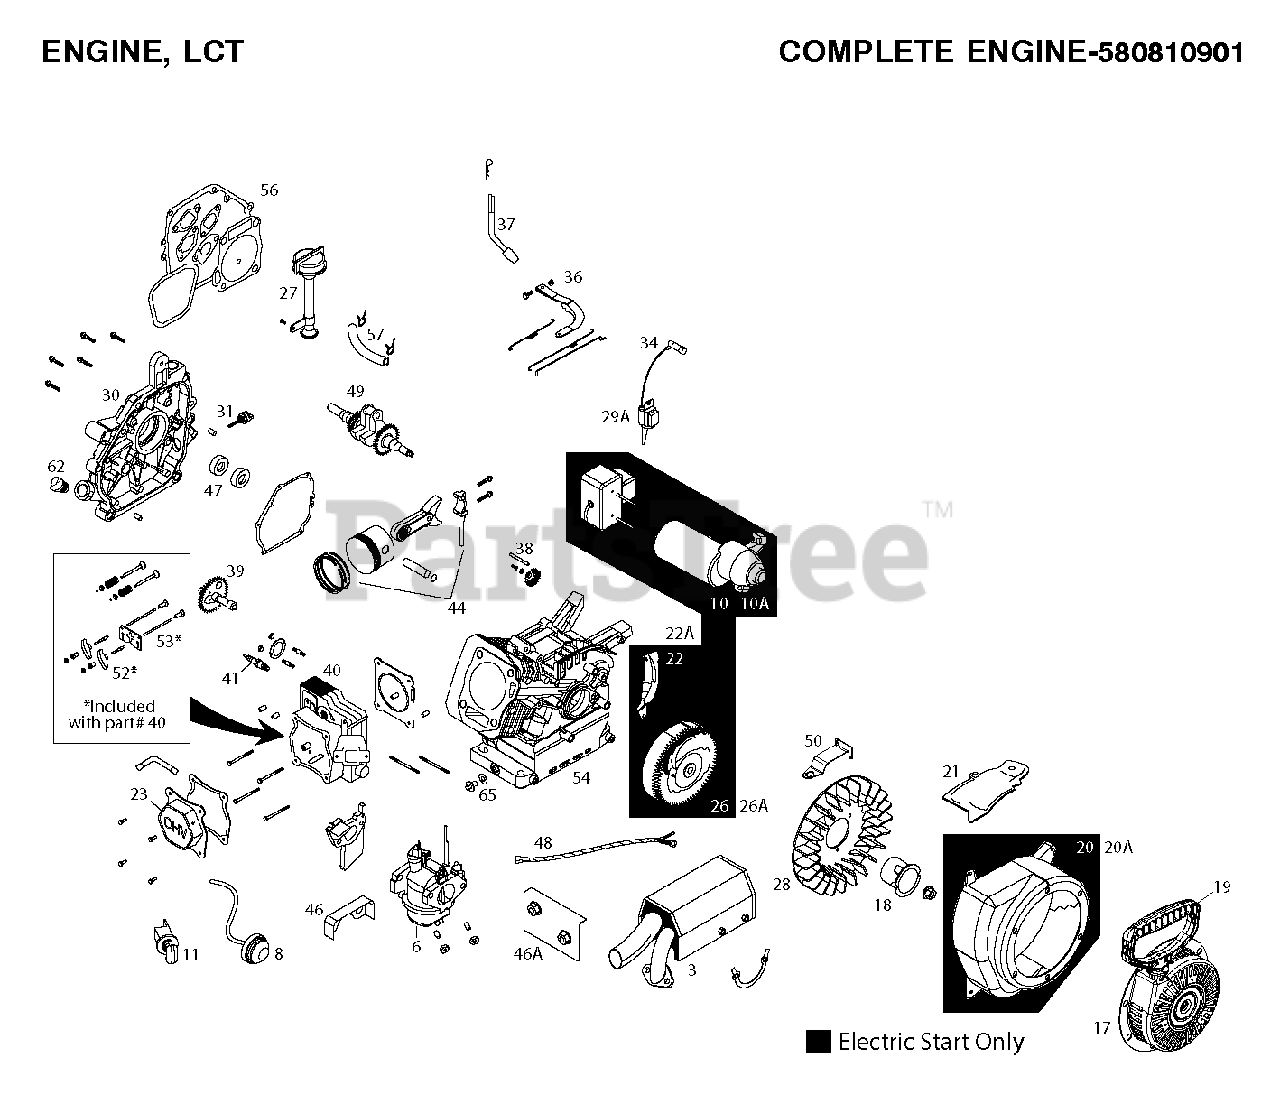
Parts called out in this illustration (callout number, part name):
3	MUFFLER.ASM.LCT.208CC.SNGL.STG
6	CARB.ASM.SS/SNO.LCT(SKSNO313)
8	BULB.FUEL.PRMR.W/HOSE(SKSNO306
10	STARTER.ASM.ELEC.(SKSNO411)
10A	STARTER STARTER.EURO
11	SWITH.KEY.ASSEM.SNOW.SINGLE.ST
17	RECOIL.STRT.ROUND(BLK) SNOW
18	STRTER.CUP(NON-SLOT)SKSN0601.2
19	STARTER.GRIP.SNOW.LCT.SKSN0603
20	BLOW.HSG.ASSY.ELECSKS
20A	BLOW.HSG.ASSY.ELEC(SKSN-0612)
21	SHILED.FLYWEEL.SYS(SKSN-0604)
22	SHLD.ELEC.START.FLY(SKSN-0605)
22A	SHIELD.FLYWEEL.MAN(SKSN-0607)
23	VALVE COVER ASSEMBLY
26	FLYWHL.ASSY.ELECT.(SKSN0405)
26A	RP KIT.FLYWHEEL.SERVICE
27	HIGH OIL-FILL TUBE ASSY
28	KIT.COOLNG.FAN.SERV(SK208-4000
29A	208CC IGN COIL (STD)
30	CRANKCASE COVER ASSY
31	DIPSTICK SMALL
34	SPARK.PLUG.BOOT.SNW,SKSN4691.1
36	KIT.GOVERNOR.ARM(SUMMER ENG)
37	KIT.GOVERNOR.CRANK(SK208-3100)
38	GOVENOR.GEARS ASM(SK2082900)
39	KIT.CAMSHAFT.208CC.LCT
40	CYLINDR.HEAD.SRV.KIT
41	SPARK.PLUG(2083810)
44	KIT.PISTON.SRV(SK208-1400)
46	SHIELD.VAPOR.SNOW
46A	SHIELD.INTAKE.(LCT.SKSN0140.1)
47	SEAL KIT (2 PCS)
48	HARNESS.WIRE/WCDI.IGN.LCT
49	CRANKSHAFT-KEYED(SK2081800.1)
50	SPEED.CTRL.BRKT.(SKSN0150)
52	ROCKER ARM KIT
53	KIT.PUSH.ROD.SRV(SK208-1001)
54	CYLINDER.ASM.SKSN0001.2
56	GASKET.KIT.208CC(SK2084300.1)
57	KIT.FUEL.HOSE.208CC.SING/STAGE
62	NON REMOVABLE PLUG
65	KIT.OIL.DRAIN.PLUG(SK2089911
